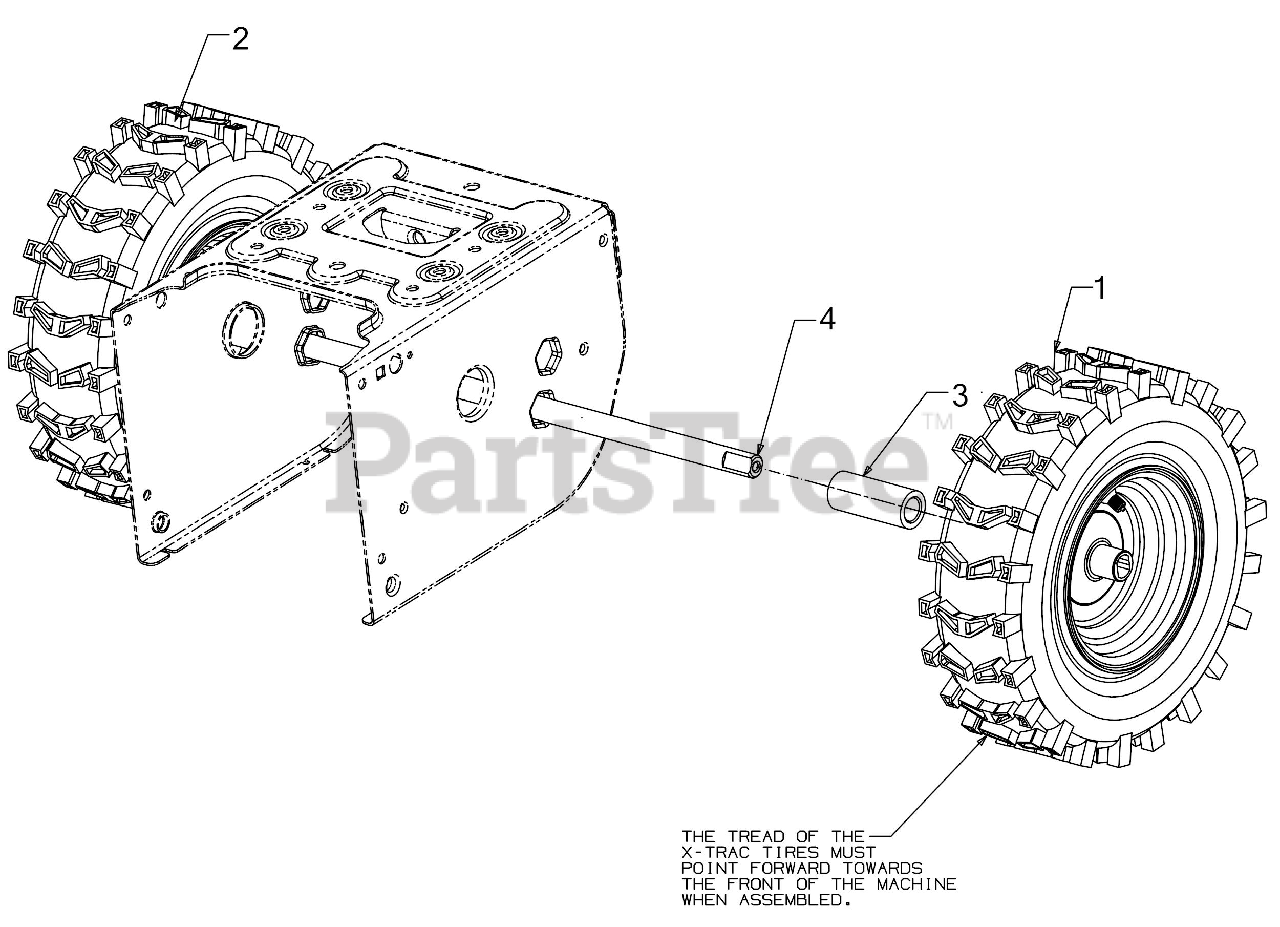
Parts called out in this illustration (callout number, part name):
1	WHEEL ASSEMBLY (13 x 4 x 6) (LH)
2	WHEEL ASSEMBLY (13 x 4 x 6) (RH)
3	WHEEL SPACER 1.25ODX.75X3.00
4	WHEEL AXLE SHAFT .75 x 22"
